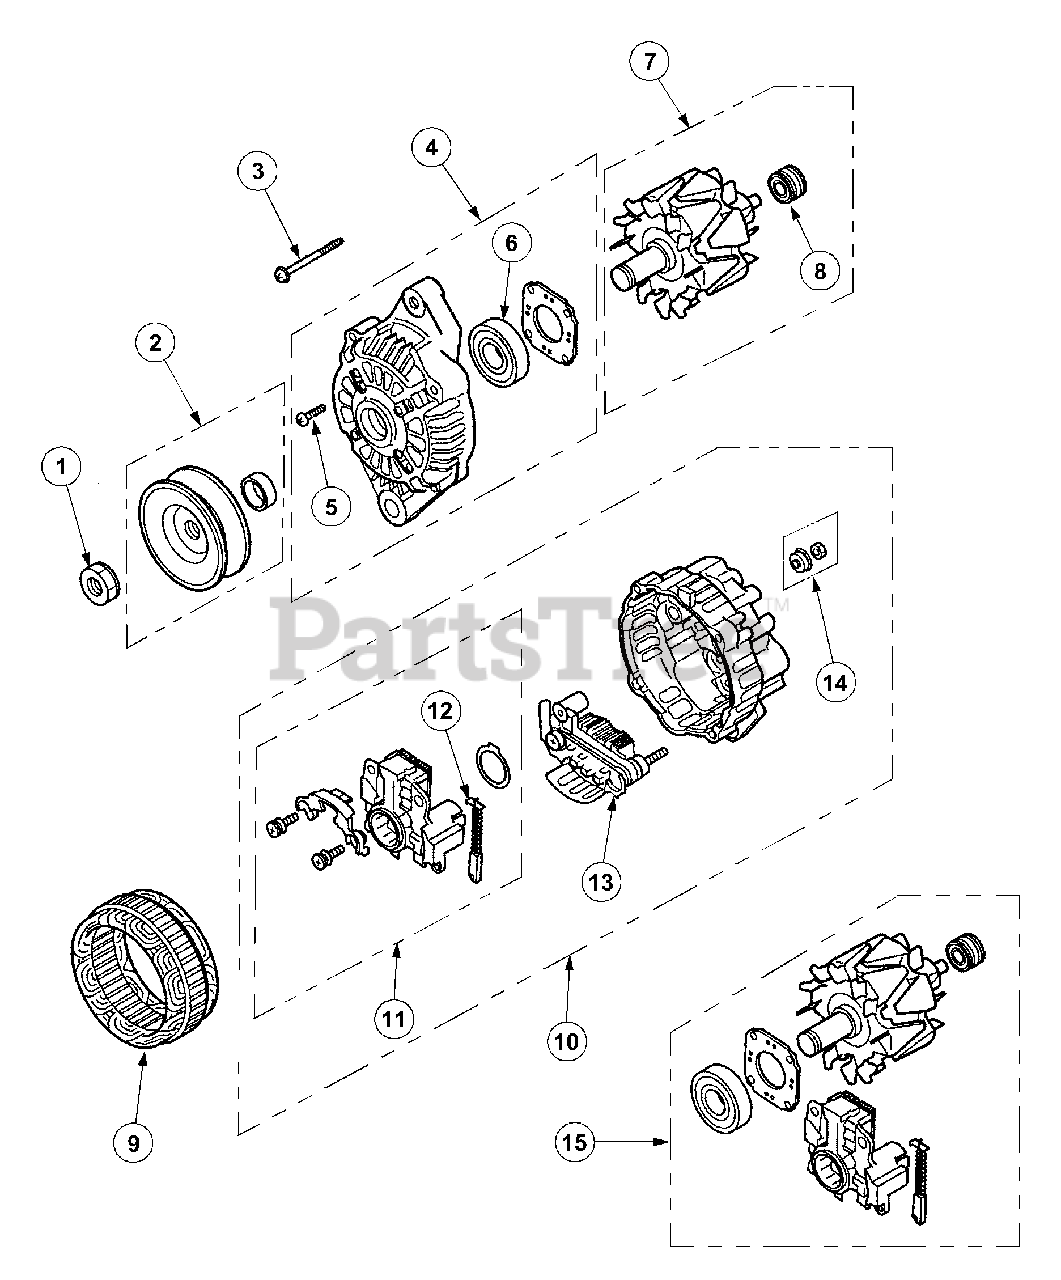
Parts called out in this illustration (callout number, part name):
3	Bolt Set
4	Bracket Ass'y
5	Screw Set
6	Bearing,Front
8	Bearing,Rear
9	Starter Ass'y
10	Bracket Ass'y
11	Regulator Set
12	Brush Set
13	Rectifier Ass'y
15	Service Kit
